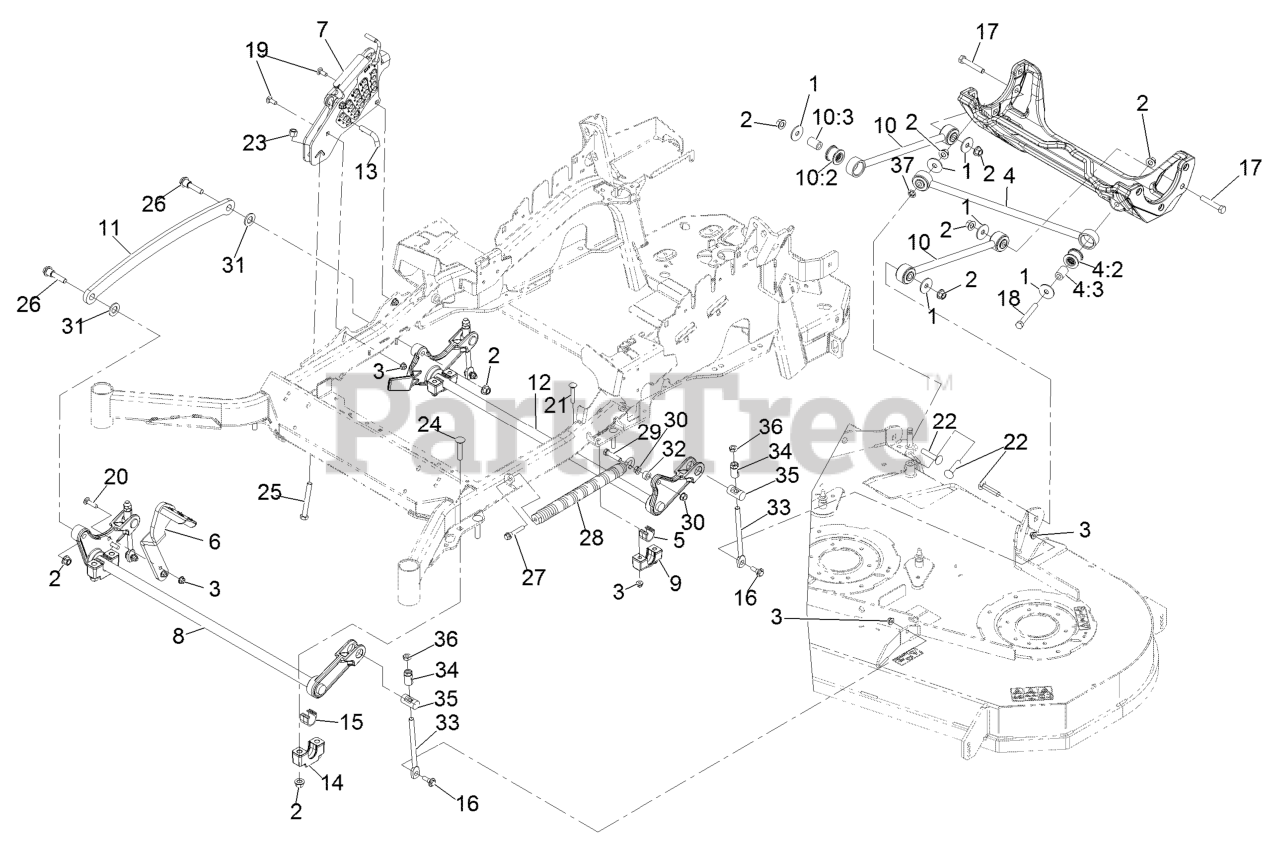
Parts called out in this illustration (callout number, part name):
1	WASHER-THRUST
2	Nut-Lock 1/2-13
3	NUT-HF, NI
4	PANHARD ROD ASM
4:2	BUSHING-SUSPENSION, RUBBER
5	BEARING-CROSS SHAFT, REAR
6	LEVER-FOOT
7	HOC ASM
8	DECKLIFT-FRONT
9	SUPPORT-CROSS SHAFT, BEARING REAR
10	DECK STRUT ASM
10:2	BUSHING-SUSPENSION, RUBBER
11	LINK-LIFT, DECK
12	LIFT-DECK, REAR
13	PIN-HOC
14	SUPPORT-CROSS SHAFT, BEARING
15	BEARING-CROSS SHAFT, FRON
16	SCREW-SHOULDER, HHF
17	SCREW-HH
18	SCREW-HH
19	BOLT-CARR
20	SCREW-CARR
21	Bolt-Carriage 3/8-16 X 2 1/4
22	SCREW-CARR
23	NUT-LOCK, NI
24	Bolt-Carriage 1/2-13 X 2 1/2 Spl Neck
25	BOLT-TAP
26	SCREW-HHF, SHOULDER
27	BOLT-SHOULDER
28	SPRING-EXTENSION
29	SCREW-HH
31	WASHER-FLAT
33	LINK-ADJUSTER, DECK LIFT
34	ADJUSTER-LIFT, DECK
35	TRUNNION
36	NUT-JAM
37	NUT-PUSH
